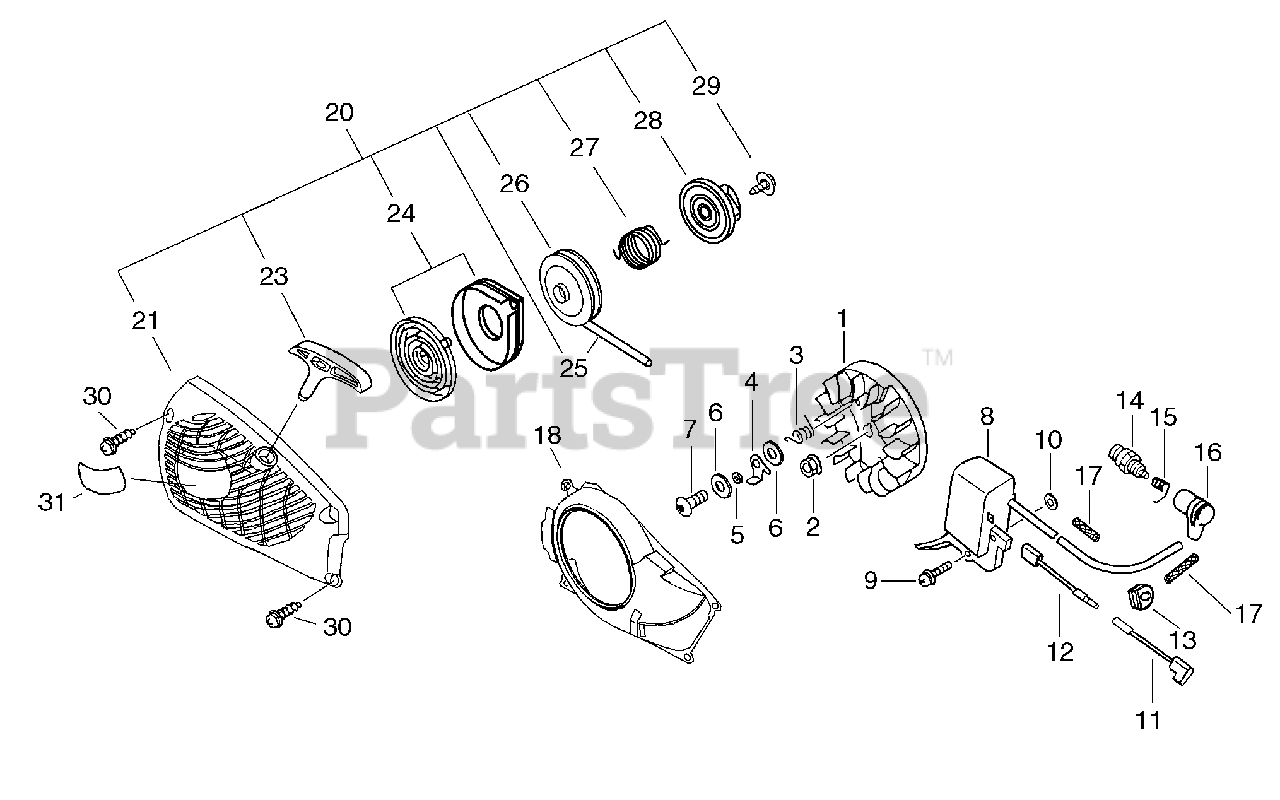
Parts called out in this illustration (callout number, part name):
1	FLYWHEEL
2	NUT - 8 -- FLANGE
3	SPRING, RETURN
4	PAWL, STARTER
6	WASHER - 5
7	SCREW - 5X14
8	COIL, IGNITION
9	SCREW - 5X22
11	LEAD - IGNITION
12	LEAD - IGNITION
14	SPARK PLUG -- BPM-7A
15	TERMINAL, SPARK PLUG CAP
16	CAP, SPARK PLUG
17	TUBE, INSULATOR
18	COVER, FAN
20	STARTER ASSY
21	STARTER ASSY
23	GRIP, STARTER
24	REWIND SPRING KIT
25	ROPE, STARTER - 3.5X900
26	REEL, ROPE
28	CATCHER, PAWL
29	SCREW
30	SCREW - 4X16
31	LABEL - ECHO
